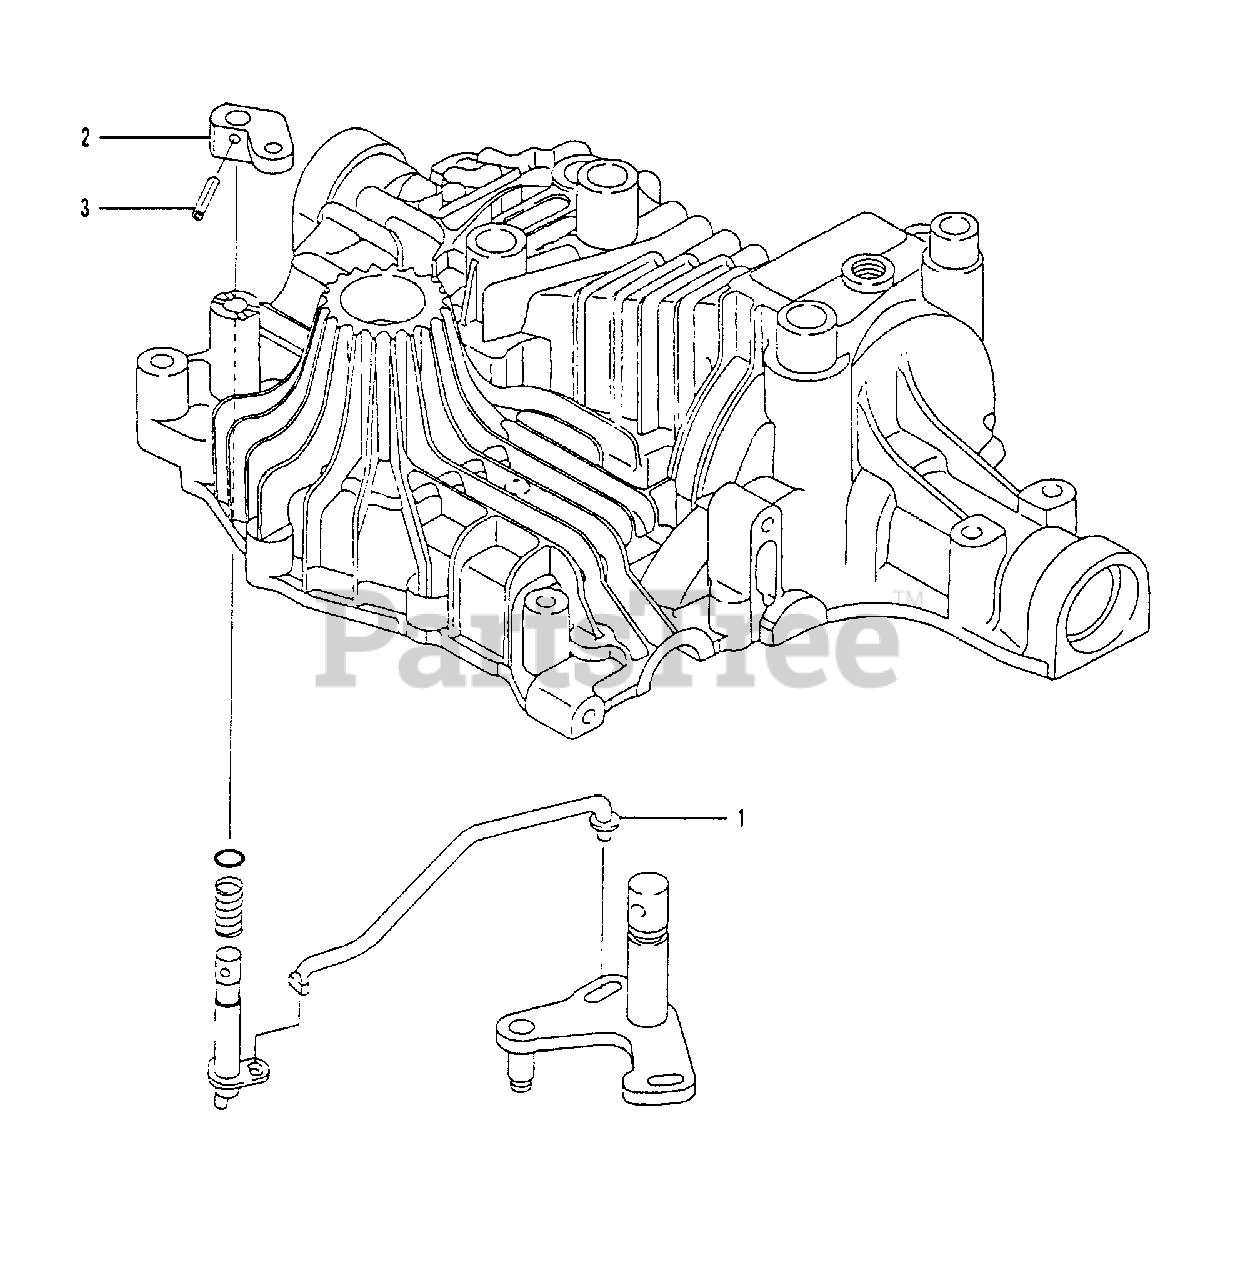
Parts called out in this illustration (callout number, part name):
1	ROD (BYPASS
2	ARM (VALVE RELEASE
3	PIN 4.0A X 25
